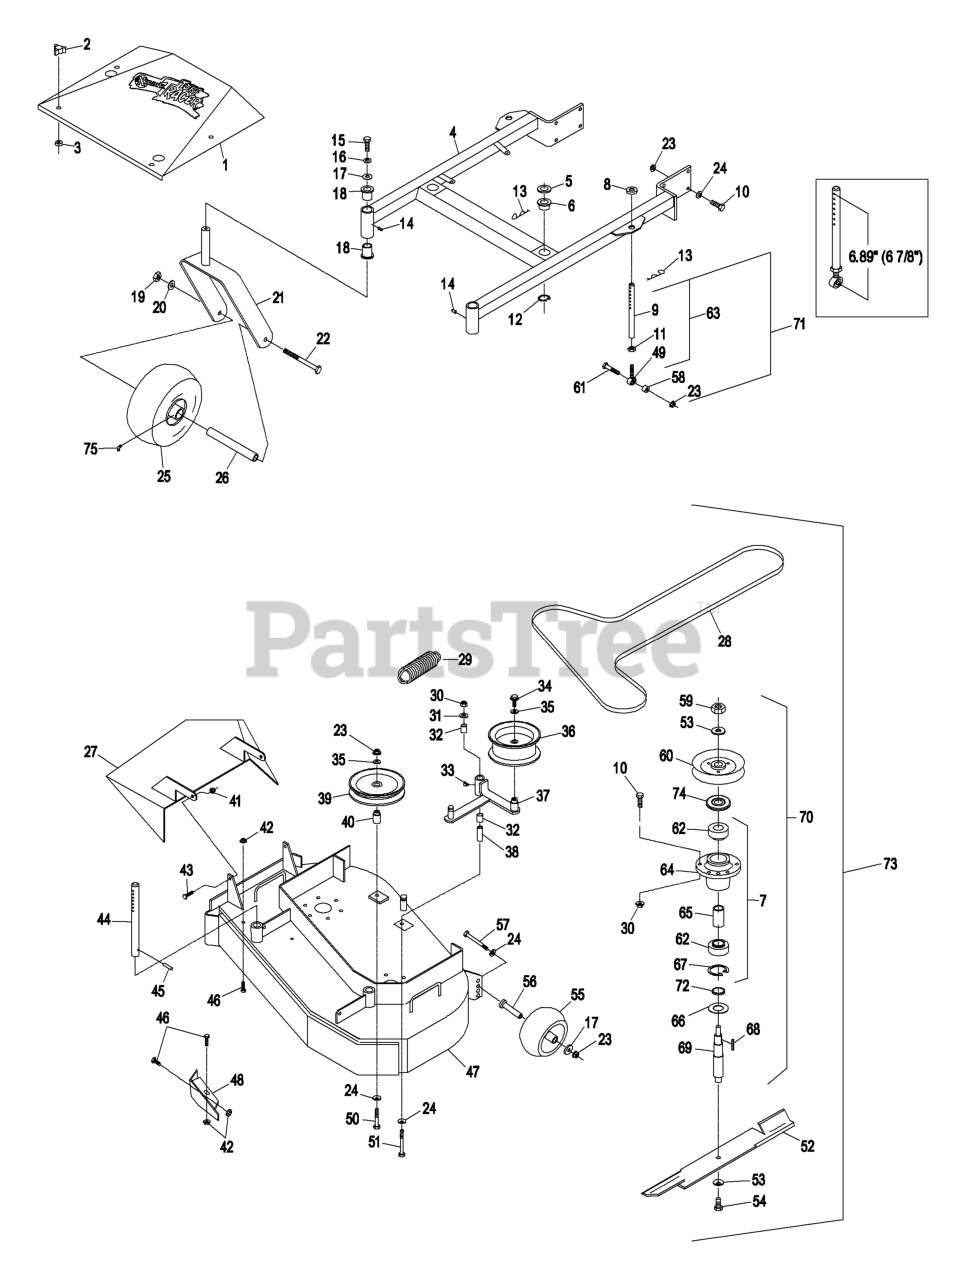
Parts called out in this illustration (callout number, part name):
2	KNOB-3 PRONG
4	DECK SUPPORT W/BSHGS 36"
5	SPACER-DECK SUPPORT
6	BUSHING-DECK
9	LINK,SUPPORT
10	SCREW-HH
11	NUT-HEX
12	RING-RETAINING
13	PIN,HAIR COTTER
14	FITTING-GREASE
15	SCREW-HH
16	WASHER-LOCK
18	BEARING-FLANGED
19	NUT-HH
20	WASHER-LOCK
22	SCREW-HH
23	NUT-HHF, WHIZ
24	WASHER-BELLEVILLE
26	SPACER FRONT CASTER
27	WLD,DISCHARGE CHUTE 36/48
28	BELT,DECK DRIVE
30	NUT-LOCK, NI
31	WASHER-FLAT
32	SLEEVE-BEARING
33	FITTING-GREASE, 90 DEG
34	SCREW-HHF
35	WASHER-FLAT
37	Arm, Weldmt
38	BUSHING-PIVOT, IDLER
39	PULLEY-IDLER
40	BUSHING-IDLER
41	NUT-LOCK, NI
43	SCREW-HH
44	ROD,DECK SUPPORT
46	SCREW-HH
47	ASM,DECK W/DECALS TTHP/MH
49	BALLJOINT
50	SCREW-HH
51	SCREW-HH
53	WASHER-SPRING
54	SCREW-CAP
55	ROLLER-SCALP, ANTI
56	BUSHING-ROLLER
57	SCREW-HH
59	NUT-HEX
60	SHEAVE,W/HUB 5.72
61	SCREW-HH
62	BEARING
65	SPACER-BEARING
66	GUARD-BEARING, BOTTOM
67	RING-SNAP
68	KEY-RECTANGLE
69	SHAFT,SPINDLE
70	HOUSING,CUTTER COMPLETE
72	SPACER-PULLEY/BEARING
73	Assembly,Cutting Deck Complete
74	GUARD-BEARING, TOP
75	FITTING-GREASE
76	KIT, SP CASTER WHEEL REPL
